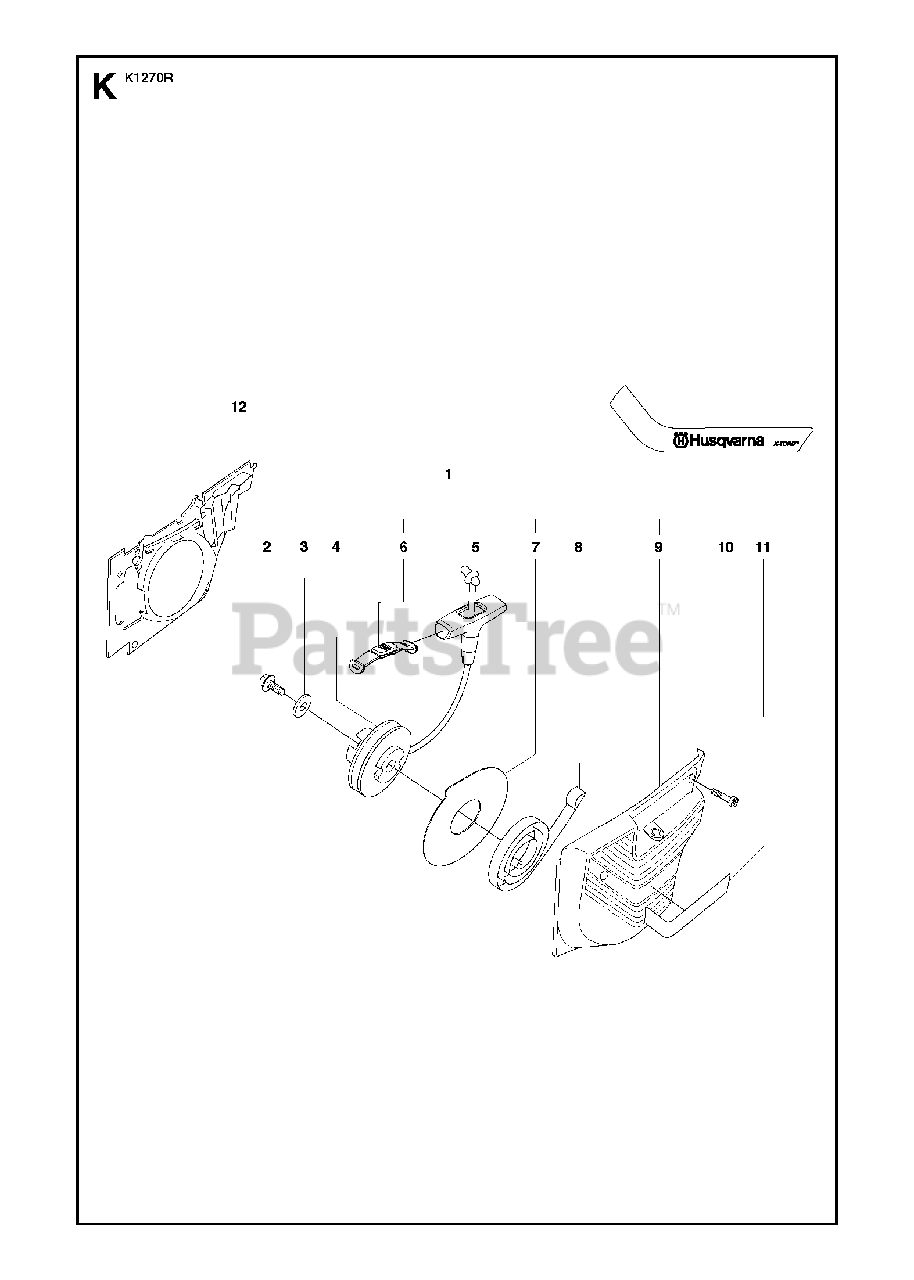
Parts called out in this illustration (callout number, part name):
2	SCREW IHSCT
5	STARTER CORD
5	STARTER CORD50 meter
6	STARTER HANDLE ASSY
7	DAMPING DISC
8	RECOIL SPRING
9	STARTER COVER
10	SCREW ITXSCM
12	AIR CONDUCTOR
12	AIR CONDUCTORRail Stop Switch only
